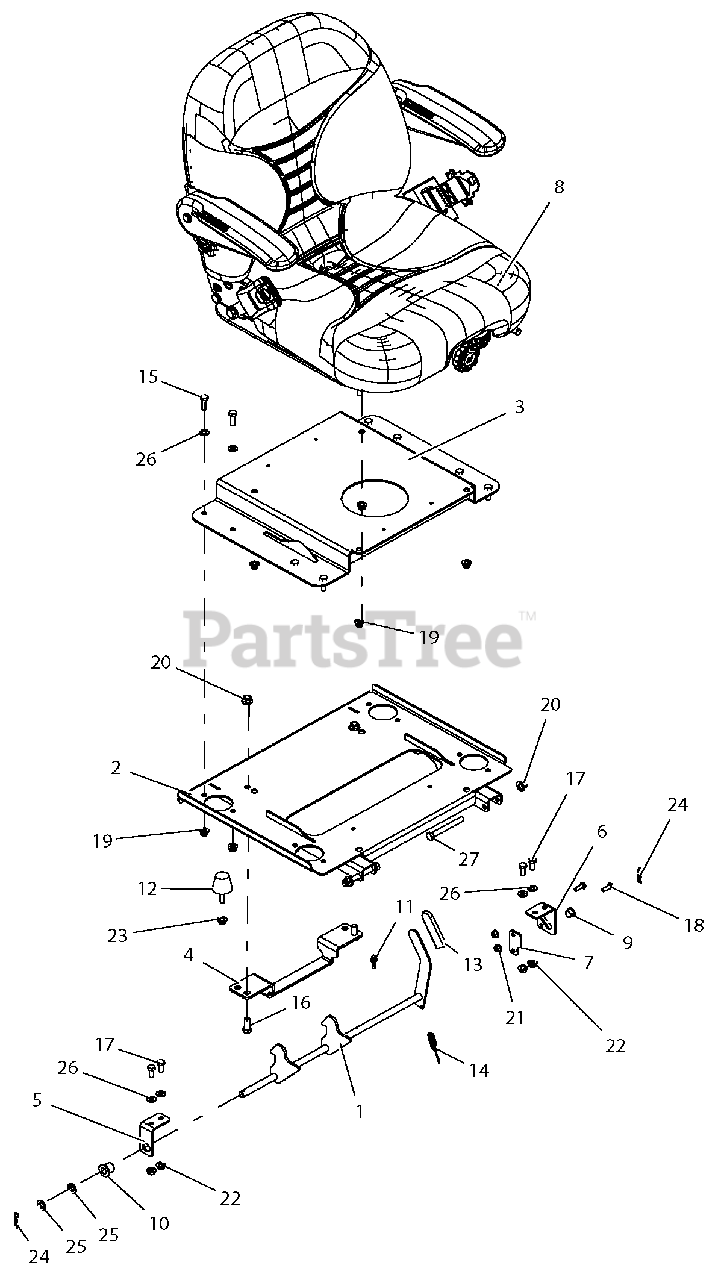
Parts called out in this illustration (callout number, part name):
1	WMT, SEAT LATCH
2	WLDMT, SEAT ISO MOUNTING-RED
3	WLDMT, SEAT BASE MOUNTING-RED
4	BRKT, SEAT LATCH-BLACK
5	MOUNT, SEAT LATCH - RH
6	MOUNT, SEAT LATCH - LH
7	RETAINER-SEAT LATCH
8	SEAT, SUSPENSION W/SEAT BELT, LT GRAY
9	BUSHING, POLYLINER - .50 SPLIT
10	BSHG, FLANGE .515 X .750 X .745 X 1.00 NYLON
11	CABLE TIE W/ TREE (.25 HOLE)
12	BUMPER, STUD MOUNTED CONE SHAPED
13	GRIP-VINYL-YELLOW .125 x 1.0 x 3.0
14	SPRG, EXTENSION
15	BLT-HEX .31-18X1.00 GR5 YWZC
16	BLT-HEX .38-16X1.00 GR5 YWZC
17	BLT-HEX .31-18X.75 GR5 YWZC
18	BLT-HEX .25-20X.75 GR5 YWZC
19	NUT-LK-NYL-FLG .31-18 YWZC
20	NUT-LK-NYL-FLG .38-16 YWZC
21	NUT, LK-TOP-FLG .25-20 YWZC
22	NUT, LK-TOP-FLG .312-18 YWZC
23	@NUT-SPNLK-FLG .312-18 YWZC
24	PIN-HAIR INT .08X.38X1.42 YWZC
25	WSHR-FL-STL .520X.827X.062 YWZC
26	WSHR-FL-STL.344X.688X.065YWZC
27	BLT-HEX .38-16X3.25 GR5 YWZC
